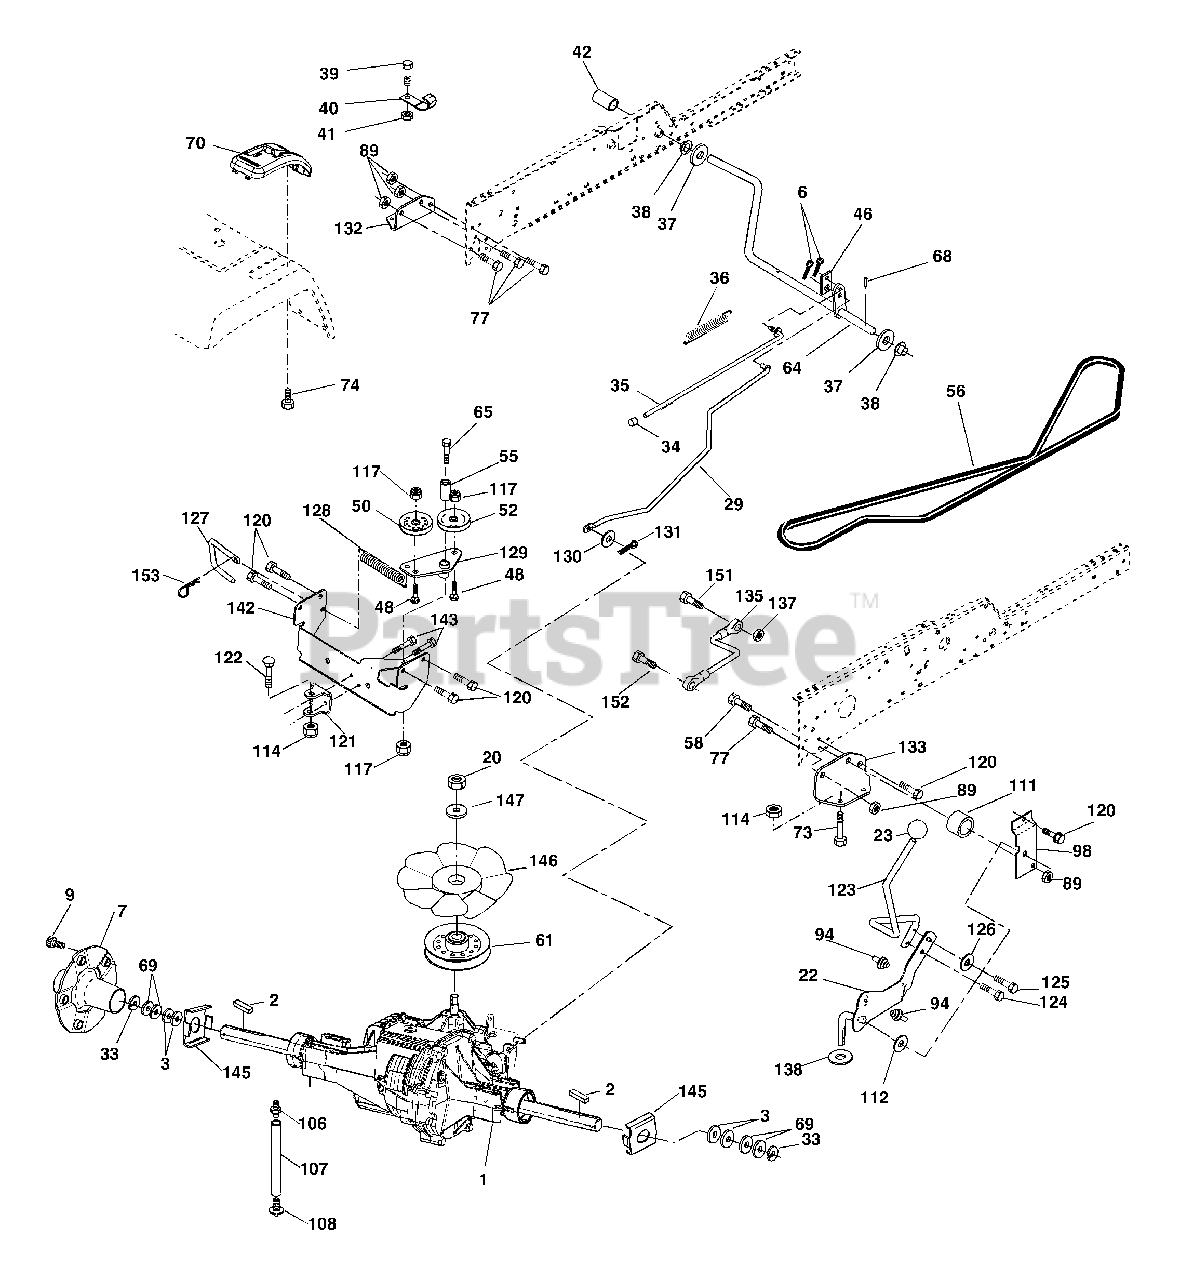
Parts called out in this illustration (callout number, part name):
2	Key Sq. 1/4 x 2.5
6	Pin, Cotter
7	Wheel, Hub Assembly
22	Lever Asm Shift
29	Brake, Rod
34	Cap, Parking Brake
35	Rod, Parking Brake
36	Spring, Drive Ground
37	Washer 25/32 x 1-1/4 x 16 Ga.
39	Screw, Fin. #10-24 x 1
40	Actuator, Interlock VGT
41	Nut Centerlock 10-24 Unc
42	Cover, Pedal
46	Retainer, Spring
48	Bolt Rdhd 3/8-16 x 1.3/4 Gr. 5
50	Pulley, Idler, Flat
52	Pulley, Idler, Grooved
55	Bearing, Idler
58	Bolt Fin Hex 7/16-14 x 1-1/2
61	Pulley, Transaxle
64	Shaft, Brake Pedal
65	Bolt, Shoulder
70	Console Automatic YT/GT
73	Bolt Hex Flghd 5/16-18 x 3 Gr5
74	Screw Hex Wsh. Hi-Lo 1/4-1/2
77	Bolt Fin Hex 7/16-14 x 1
89	Nut Crownlock 7/16-14 Unc
94	Fastener Christmas Tree
98	Bracket Shift
106	O-Ring Asm Hydro Gear
107	Line Fuel Hydro 15" VGT
108	Cap Asm Vent Hydro Gear
111	Spacer Shift Lever VGTH
112	Washer Nylon High Temp
114	Nut Lock Hex W/Ins 5/16-18 Unc
117	Nut, Lock Flg. 3/8-16
120	Screw 3/8-16 x .75
121	Bracket Strap Torque
122	Bolt RDHDSQ 5/16-18 Unc x 2-1/2
124	Bolt Shoulder 5/16-18 x .561
125	Screw 5/16-18 x 5/8
126	Washer SRRTD 5/16 ID x 1.0 x .125
127	Link Control Clutch
128	Spring Drive GRND
129	Bracket Asm Idler Tensioning
130	Washer 13/32 x 5/8 x 16 Ga.
131	Pin Cotter 3/32 x 3/4
132	Bracket Mtg Hydro 3500 LH VGT
133	Bracket Mtg Hydro 3500 RH VGT
135	Link Asm Control Hydro 3500
137	Nut Lock 5/16-18 NC Thd.
138	Washer Thrust 5/8 x 1.10 x 1/32
142	Strap Torque HG-3500
143	Screw Thdrol 5/16-18 x 3/4
145	Washer Axle Flange HG-3000
146	Fan 7" Hydro
148	Screw 3/8-16 x 1-1/4
151	Bolt Hex 5/16-18 x 7/8
152	Bolt Hex 5/16 x 1 W/Patch
153	Spring, Retainer
